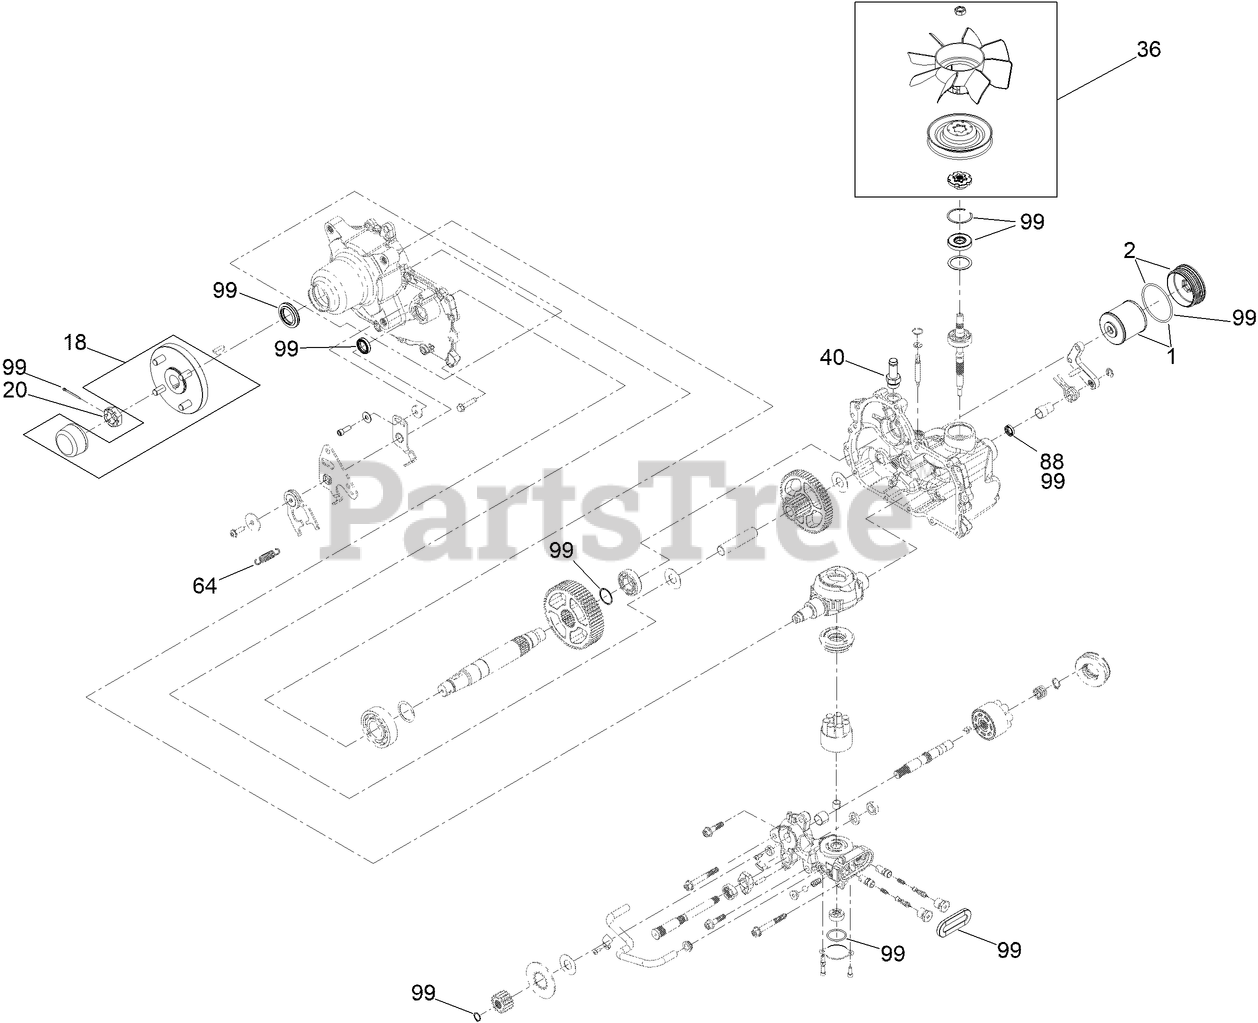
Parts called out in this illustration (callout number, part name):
1	KIT, FILTER
2	KIT, FILLER CAP
18	HUB-4 BOLT
20	NUT, SLOTTED
36	KIT, FAN AND PULLEY
40	FITTING-5/8 BEADED, 7/8 SAE
64	SPRING-EXTENSION
88	SEAL, BRAKE
99	KIT, SEAL
